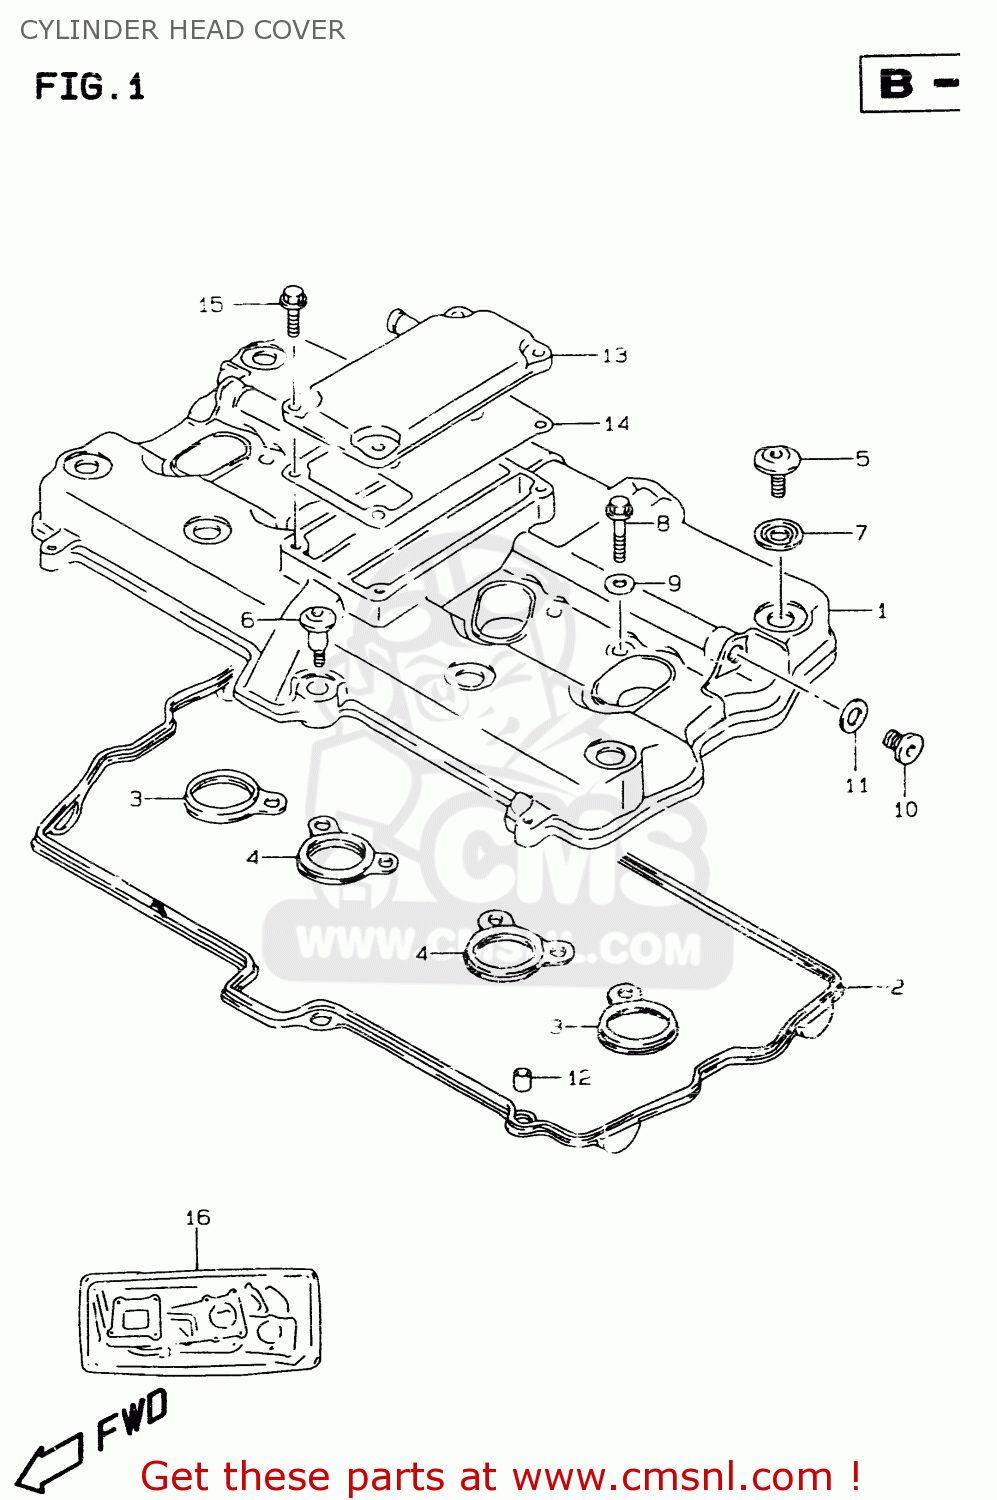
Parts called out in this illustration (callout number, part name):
1	COVER,CYLINDER HEAD
2	GASKET,CYLINDER HEAD COVER (NAS)
3	GASKET,HEAD COVER NO.2 (NAS)
4	GASKET,HEAD COVER NO.3 (NAS)
5	BOLT(7X17.5)
6	BOLT(7X31)
7	WASHER(10.6X25.5X2.3)
8	BOLT,UNION 8X35
9	GASKET 8.2X14X1 (NAS)
10	PLUG(L:12)
11	GASKET(12.1X16.2X3.7) (NAS)
12	PIN
13	COVER,BREATHER
14	GASKET,BREATHER COVER
15	BOLT
16	GASKET SET (NAS)
